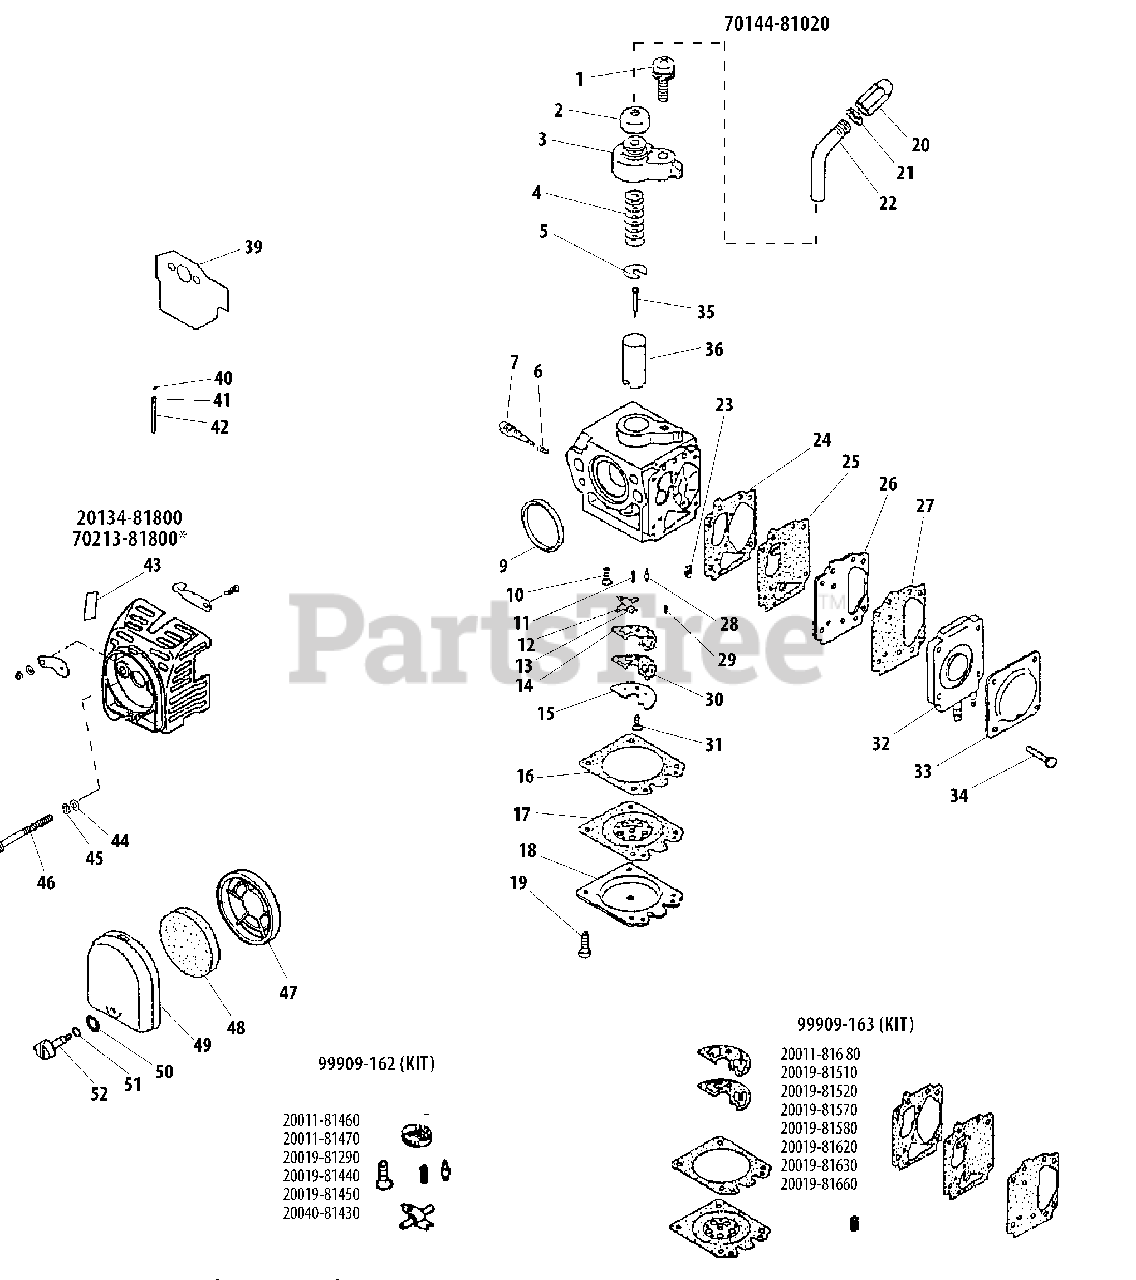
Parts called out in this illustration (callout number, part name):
1	SCREW - 5X15
2	GROMMET
3	CAP, CARBURETOR
4	SPRING, THROTTLE
5	RETAINER
6	SCREW, IDLE ADJUST
7	SCREW, IDLE ADJUST
9	SEAL
10	SCREW, METERING LEVER PIN
11	SPRING
12	PIN, METERING LEVER
13	LEVER, METERING
14	GASKET
15	PLATE
16	GASKET, METERING
17	DIAPHRAGM, METERING
18	COVER, DIAPHRAGM
19	SCREW
20	NUT, CABLE ADJUST
21	LOCKNUT
22	GUIDE, CABLE
23	STRAINER
24	GASKET, PUMP
25	DIAPHRAGM, PUMP
26	PLATE, PUMP
27	GASKET, PUMP
28	VALVE, INLET NEEDLE
29	SPRING
30	VALVE, CHECK
31	SCREW, METERING LEVER PIN
32	COVER, PUMP
33	COVER, DIAPHRAGM
34	SCREW - 3X14
35	NEEDLE, JET
36	VALVE, THROTTLE
39	GASKET
40	RING, RETAINING - 6
41	SPRING
42	PIPE
43	LABEL - CHOKE
44	WASHER - 5
45	LOCKWASHER - 5
46	SCREW - 5X60
47	BRACKET, FILTER
48	FILTER, AIR - FOAM
49	COVER, AIR FILTER
50	O-RING
51	WASHER - CONICAL
52	THUMBSCREW
A	CARBURETOR
A	AIR FILTER CASE ASSY
A	AIR CLEANER CASE ASSY - BLUE
A	REPAIR KIT
A	DIAPHRAGM/GASKET KIT
